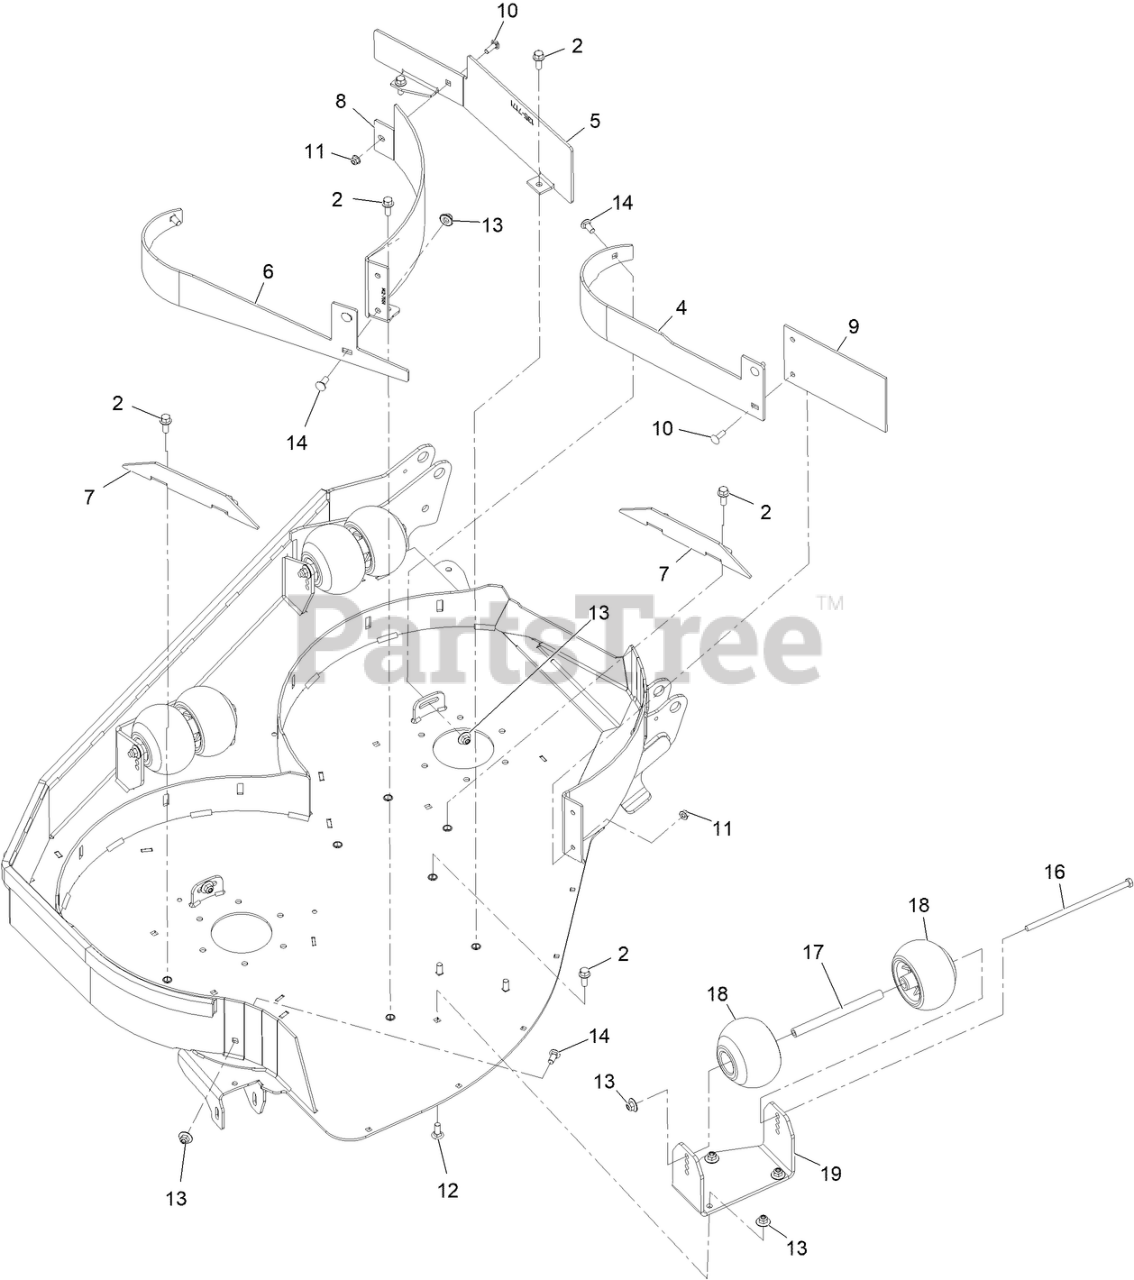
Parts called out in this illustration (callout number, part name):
2	SCREW-HHF
4	BAFFLE-DOGLEG, RH
5	BAFFLE-CTR
6	BAFFLE-DOGLEG, OUTSIDE
7	PLATE-BAFFLE STRAIGHT RH
8	BAFFLE-WING REAR CENTER
9	FLAP-RUBBER
10	SCREW-CARR
11	NUT-HF, NI
12	BOLT-CARR
13	Nut-Nyloc 3/8-16 Flg
14	BOLT-CARR
16	SCREW-HH
17	SPACER-WHEEL
18	ROLLER-SCALP, ANTI
19	PLATE-REAR AS BRACKET
